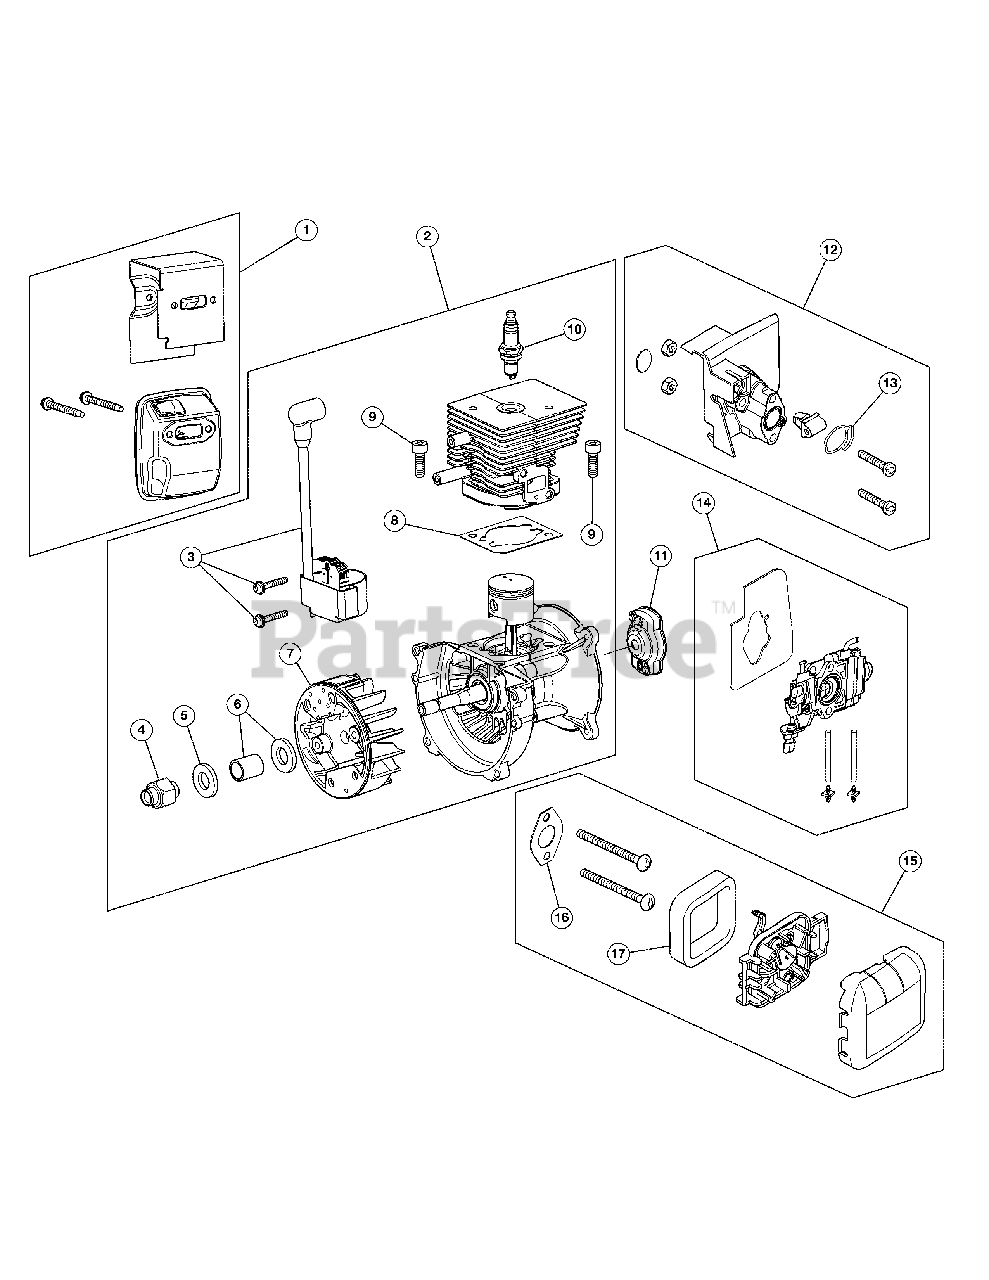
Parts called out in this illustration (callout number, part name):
1	Muffler Assembly
2	Shortblock Assembly (Incl. 3 - 10)
3	Module Assembly
4	Flywheel Adaptor
5	Washer
6	Bushing
7	Flywheel Assembly
8	Cylinder Gasket
10	Spark Plug
11	Pawl Assembly
12	Insulator Assembly (Incl. 13)
13	Insulator O-Ring
14	Carburetor Assembly
15	Air Cleaner Assembly (Incl. 16 and 17)
16	Carburetor Gasket
17	Air Filter
